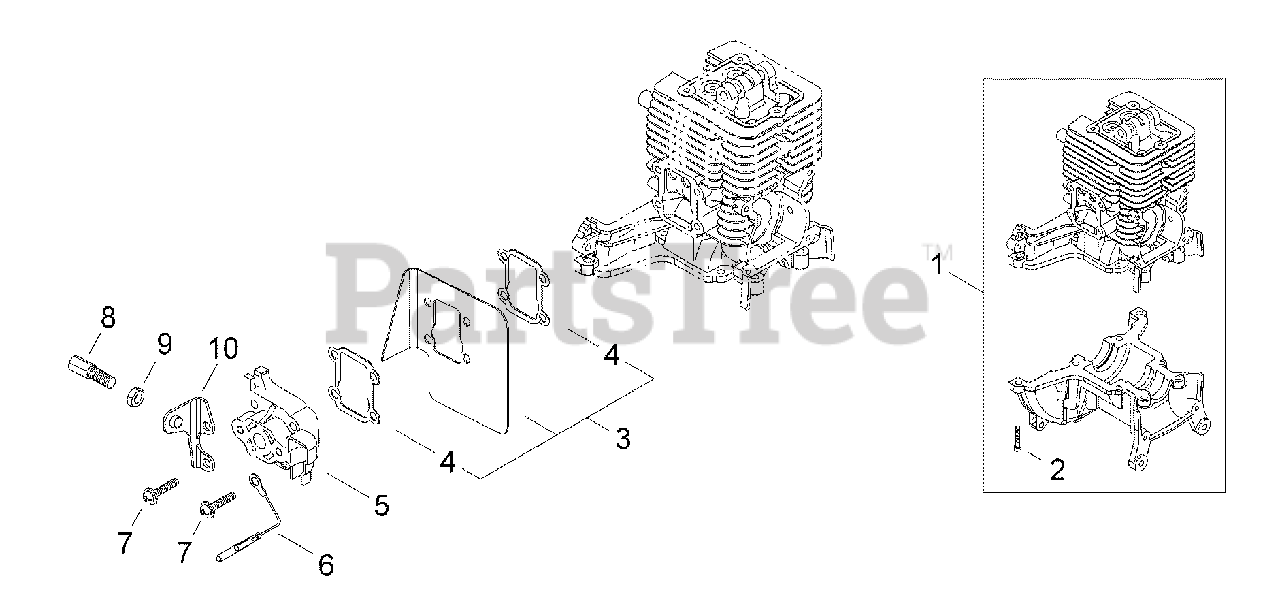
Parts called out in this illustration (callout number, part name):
1	CYLINDER & CRANKCASE ASSY
2	BOLT 5×16
3	SHIELD ASSY, INTAKE HEAT
4	GASKET, EXHAUST
5	INSULATOR WITH REED VALVE
6	LEAD - GROUND L= 110 MM
7	SCREW M5×25
8	ADJUSTER, THROTTLE CABLE
9	NUT, ADJUSTER LOCK M6
10	BRACKET, THROTTLE CABLE
